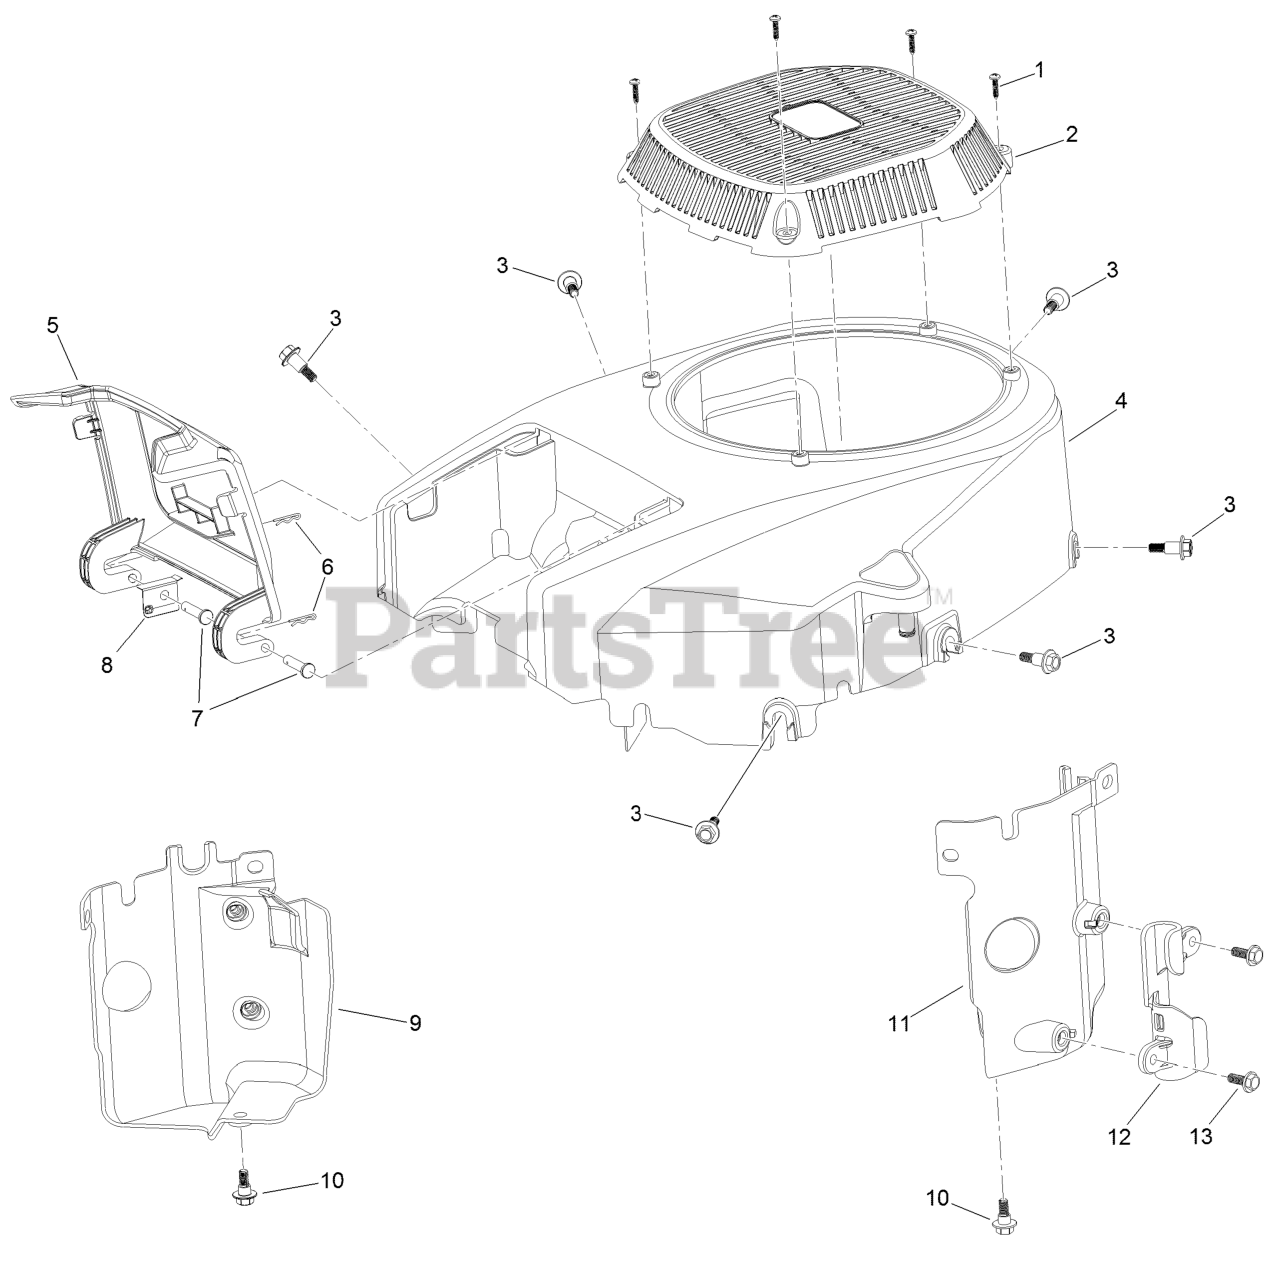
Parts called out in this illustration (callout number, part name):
1	SCREW-PLASTIC, PPH
2	COVER-FAN
3	SCREW-SHOULDER, HWH
5	DOOR-FILTER, AIR
6	PIN-HAIR
8	PLATE-SPRING
9	BAFFLE-AIR, LEFT
10	SCREW-SHOULDER, HHF
11	BAFFLE-AIR, RIGHT
12	CLEAT-HOSE
13	SCREW-HHF
